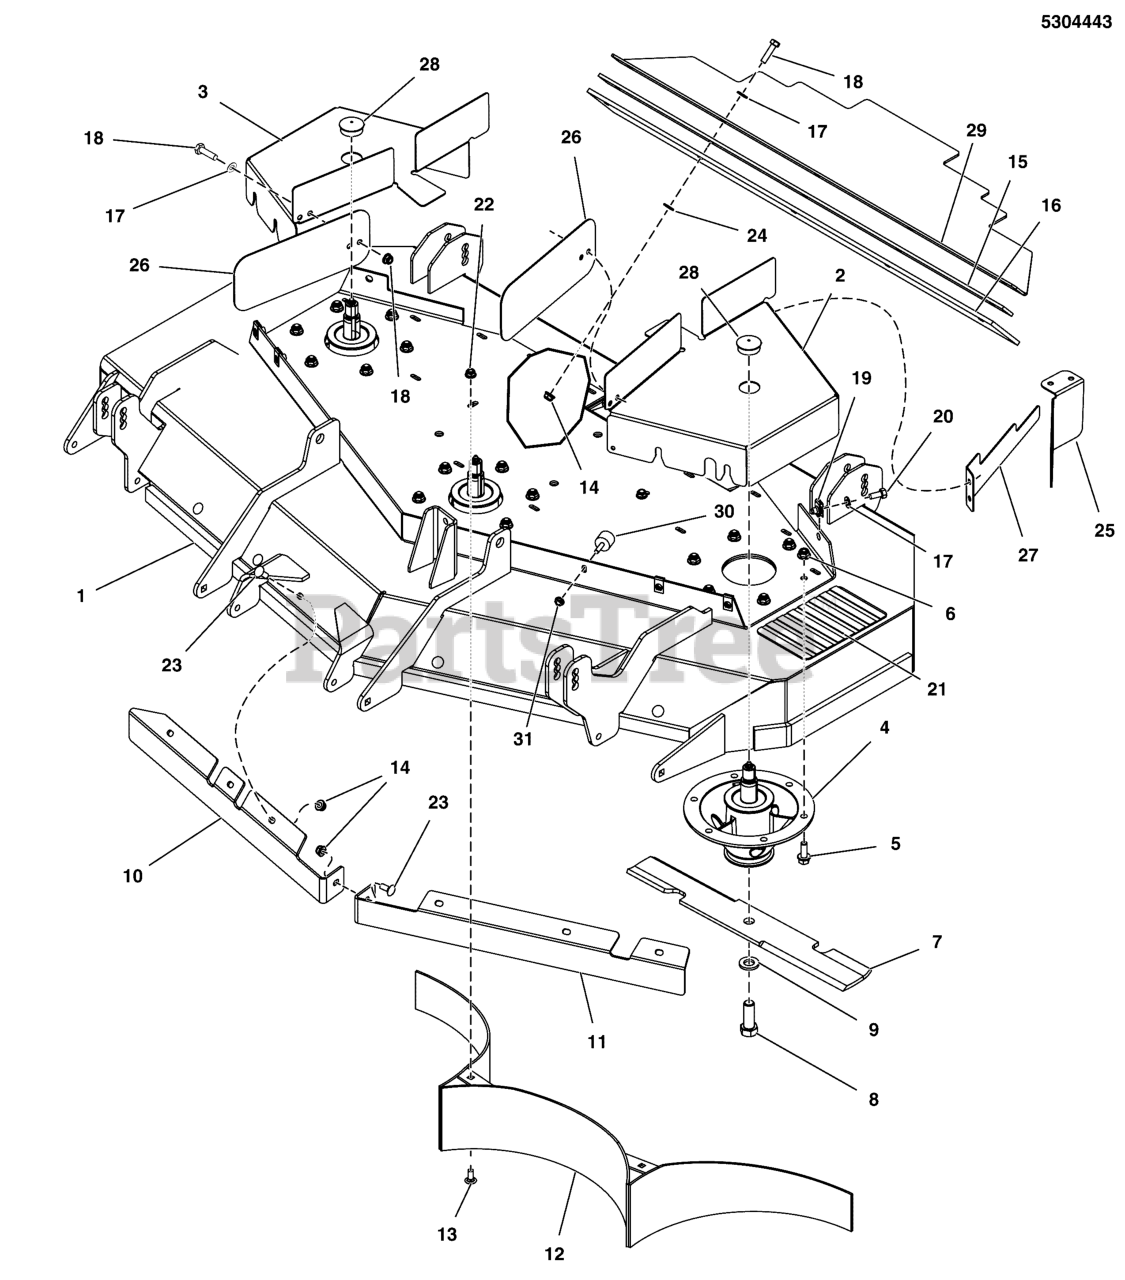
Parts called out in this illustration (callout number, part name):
1	DECK SHELL W/DECALS,52RDCE,2600,5414519B
1	DECK SHELL W/DECALS, 2600-52E (5416973B)
2	PLATE, GUARD, DECK, LH, 52 CE - RED
3	PLATE, GUARD, DECK, RH, 52 CE - RED
4	SPINDLE ASSM, CAST IRON 8.0 - 6-BOLT
5	BOLT, 3/8-16 X 1, FLANGE, GD 5, CZ
6	NUT, 3/8 - 16 HEX NYLOCK FLANGE
7	BLADE SET, MULCH, 52 DECK (SET OF 3)
8	BOLT, 5/8-11 X 1-3/4 GD8
9	WASHER, BLADE BOLT, 9/16" F436, CZ
10	BAFFLE, FRONT DISCHARGE RH - RED
11	BAFFLE, FRONT DISCHARGE LH - RED
12	WELD, REAR BAFFLE, SHRT - BLK
13	BOLT, 5/16-18 X 3/4, CARRIAGE, GD5, CZ
14	NUT, 5/16-18 HEX NYLOCK FLANGE NUT
15	PLATE, FLAP RETAINER, 2000 RD - BLK
16	FLAP, 2000 REAR DISCHARGE
17	WASHER, 5/16" SAE
18	BOLT, 5/16-18 X 1" GRD5 YZ
19	BODY CLIP, 5/16-18-7GA MATERIAL
20	BOLT, 5/16-18 X 3/4 GD5
21	SAFETY WALK, 9.75 X 6.00
22	NUT, 5/16-1/8, HEX, CNTR LK, ZINC PHOS/OIL
23	BOLT, 5/16-18 X 1, CARRIAGE, GD5, CZ
24	5/16" PUSH-ON NUT RETAINER, STL, CZ
25	PLATE,DECK BELT GUARD,REAR,RH 52CE - RED
26	PLATE, GUARD, DECK - IS2600Z EU - RED
27	PLATE,DECK BELT GUARD,REAR,LH 52CE - RED
28	PLUG, PANEL, 1.25 - BLACK
29	PLATE, REAR DEFLECTOR, 52RD - BLK
30	BUMPER, RUBBER, 1/4-20
31	NUT, 1/4-20 HEX SERR. FLANGE
